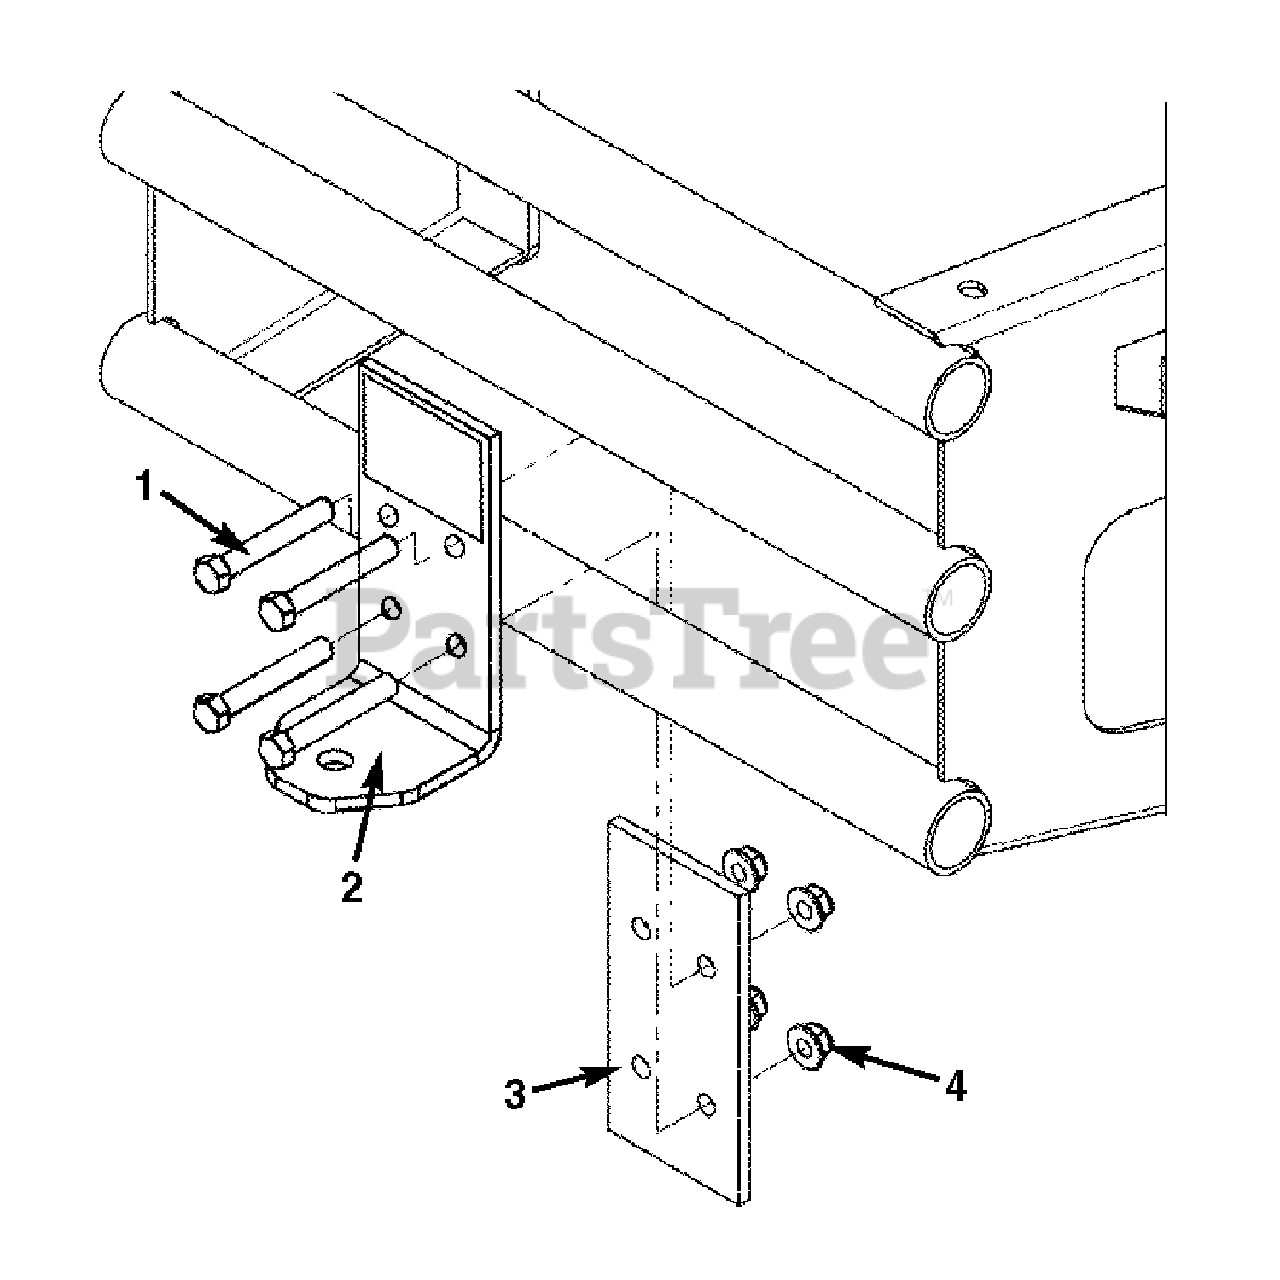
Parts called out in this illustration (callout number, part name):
1	BOLT, 3/8-16 X 2-1/2" GD5 CZ
2	Hitch Plate Assembly
3	Back Plate
4	3/8-16 Nylock Flange Nut
